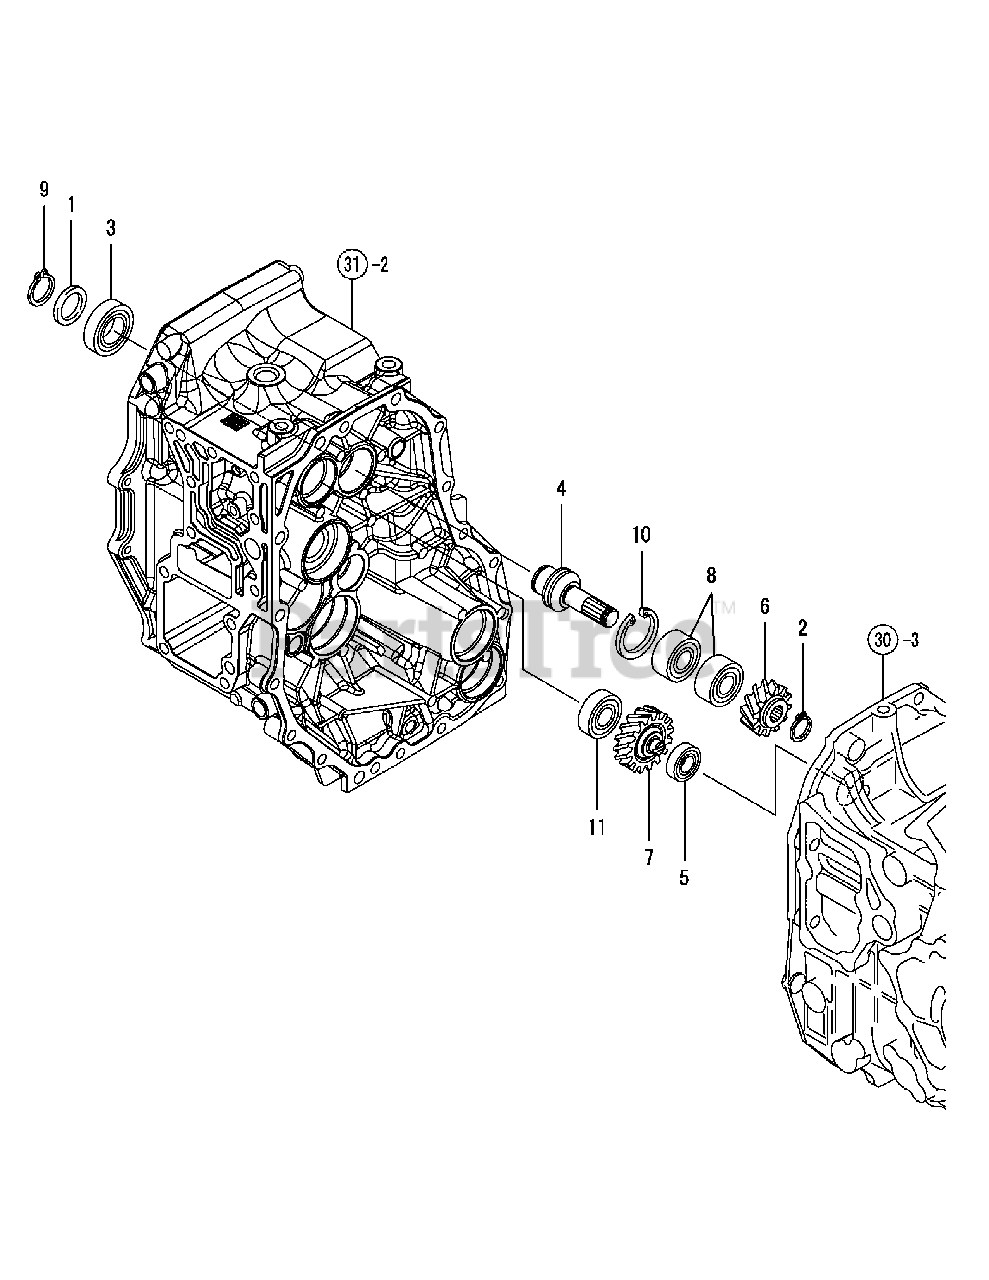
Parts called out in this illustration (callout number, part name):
1	Spacer 25*33*2
3	Bearing, Tmb005
4	Shaft Assy, Input
5	Ball Bearing 6201
6	Gear, PTO Drive Z=15
7	Gear, Idle Z=18T
